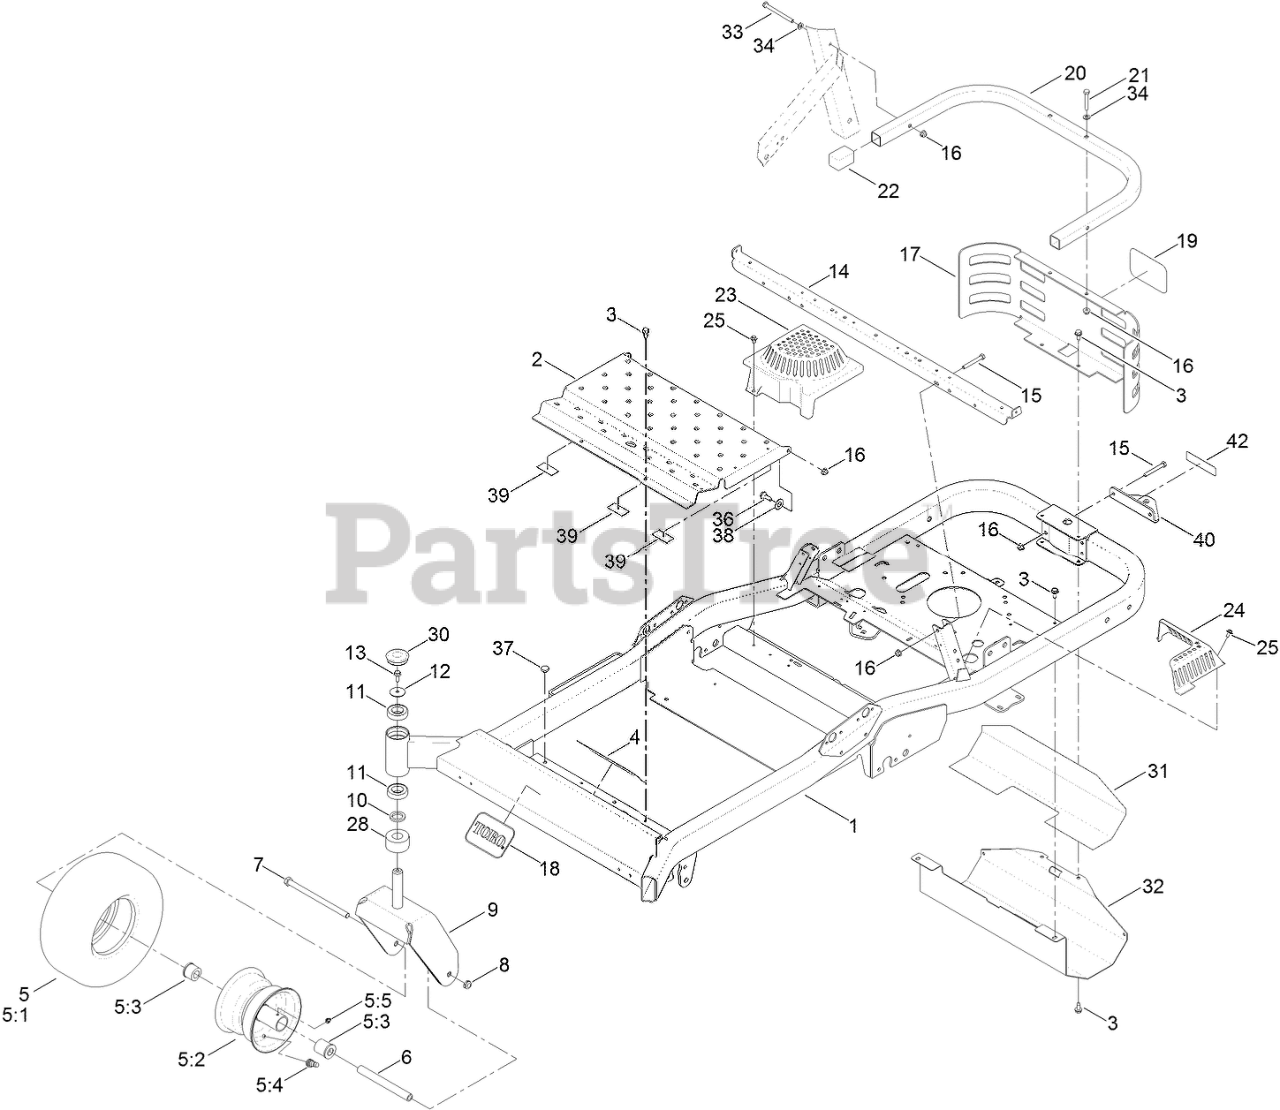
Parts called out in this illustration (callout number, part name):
1	FRAME ASM
2	PAN-FLOOR
3	SCREW-HWHTF
4	DECAL-DANGER
5	TIRE AND WHEEL ASM
5:1	TIRE-13 INCH SMOOTH
5:2	RIM-6 INCH
5:3	BUSHING-FLANGE
5:4	STEM-VALVE
5:5	FITTING-GREASE
6	SPANNER
7	SCREW-HH
8	NUT-LOCK, NI
9	FORK-CASTER
10	WASHER-THRUST
11	BEARING-BALL
12	WASHER-FLAT
13	SCREW-HHF
14	SUPPORT-SEAT
15	SCREW-HH
16	NUT-HF, NI
17	GUARD-REAR
18	DECAL
20	TUBE-GUARD
21	SCREW-HH
23	COVER-FAN, RH
24	COVER-FAN, LH
25	SCREW-HHFTF
28	SPACER-CASTER
30	CAP-GREASE
31	FOIL-HEAT SHIELD
32	SHIELD-HEAT
33	SCREW-HH
34	WASHER-PLAIN
36	SCREW-SHOULDER
37	BUMPER
38	WASHER-TEFLON
39	PAD-RUBBER
40	BRACKET-HITCH
